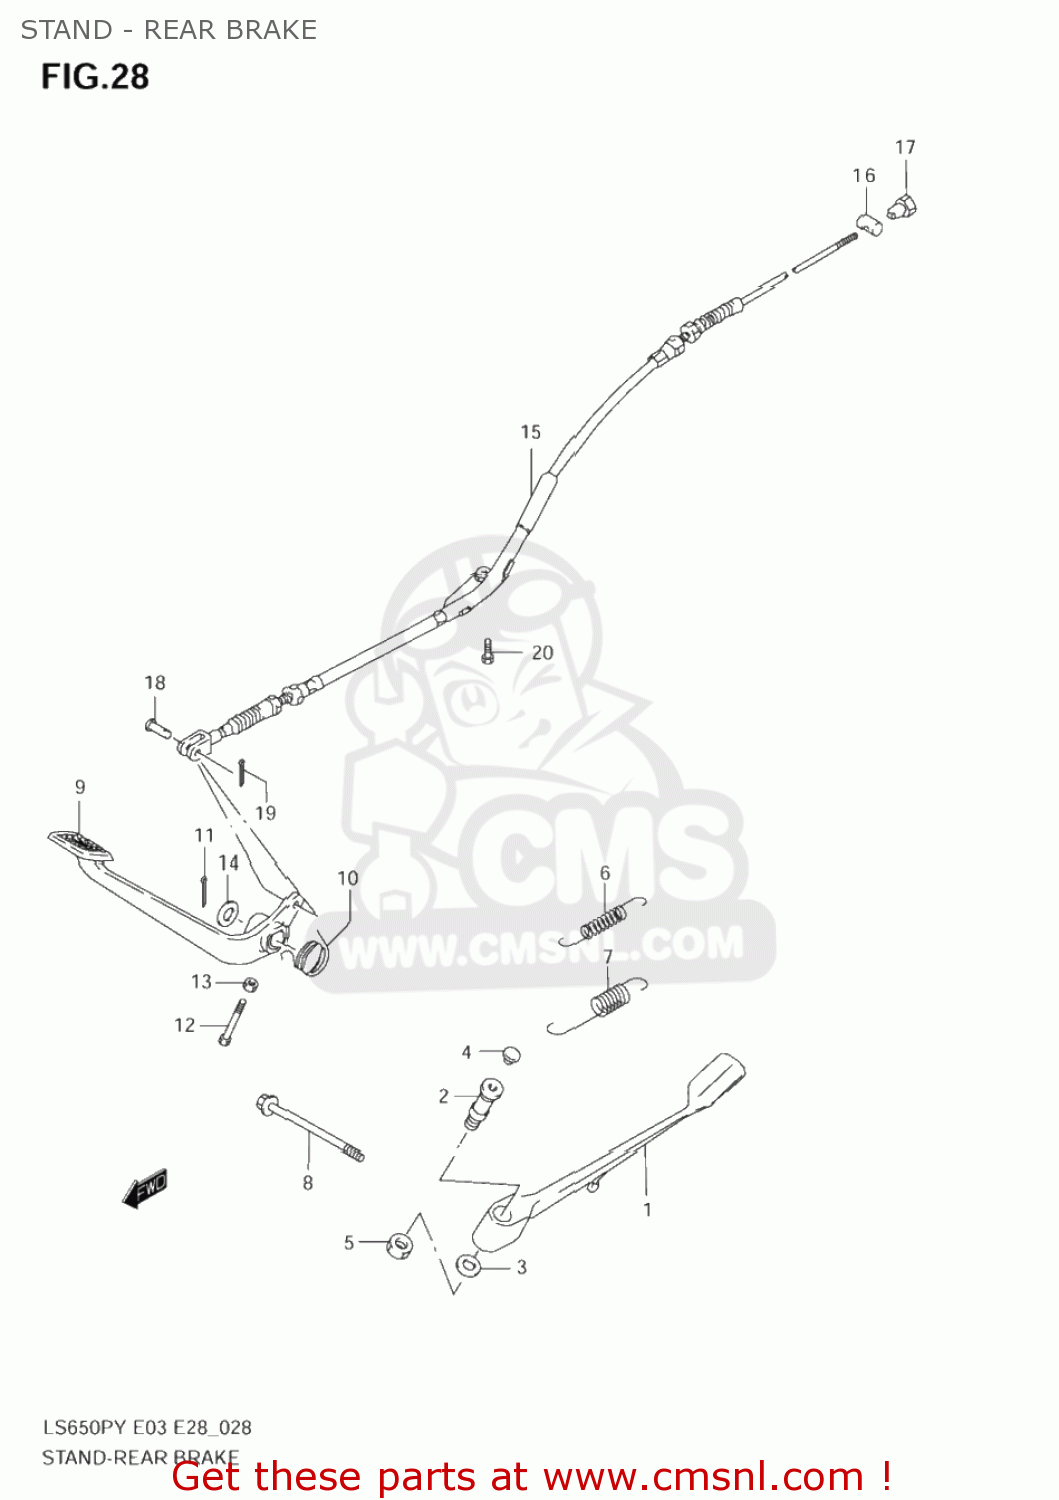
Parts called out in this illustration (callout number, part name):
1	STAND,PROP
2	BOLT,PROP STAND
3	THRUST WASHER
4	CAP,PROP STAND BOLT
5	NUT
6	SPRING
7	SPRING
8	BOLT(10X105)
9	PEDAL,BRAKE
10	SPRING
11	COTTER PIN
12	BOLT(6X31)
13	NUT 6MM
14	WASHER(16.5X22X1)
15	CABLE,RR BRAKE
16	PIN(13X18)
17	NUT
18	PIN(L:17.5)
19	PIN
20	BOLT
